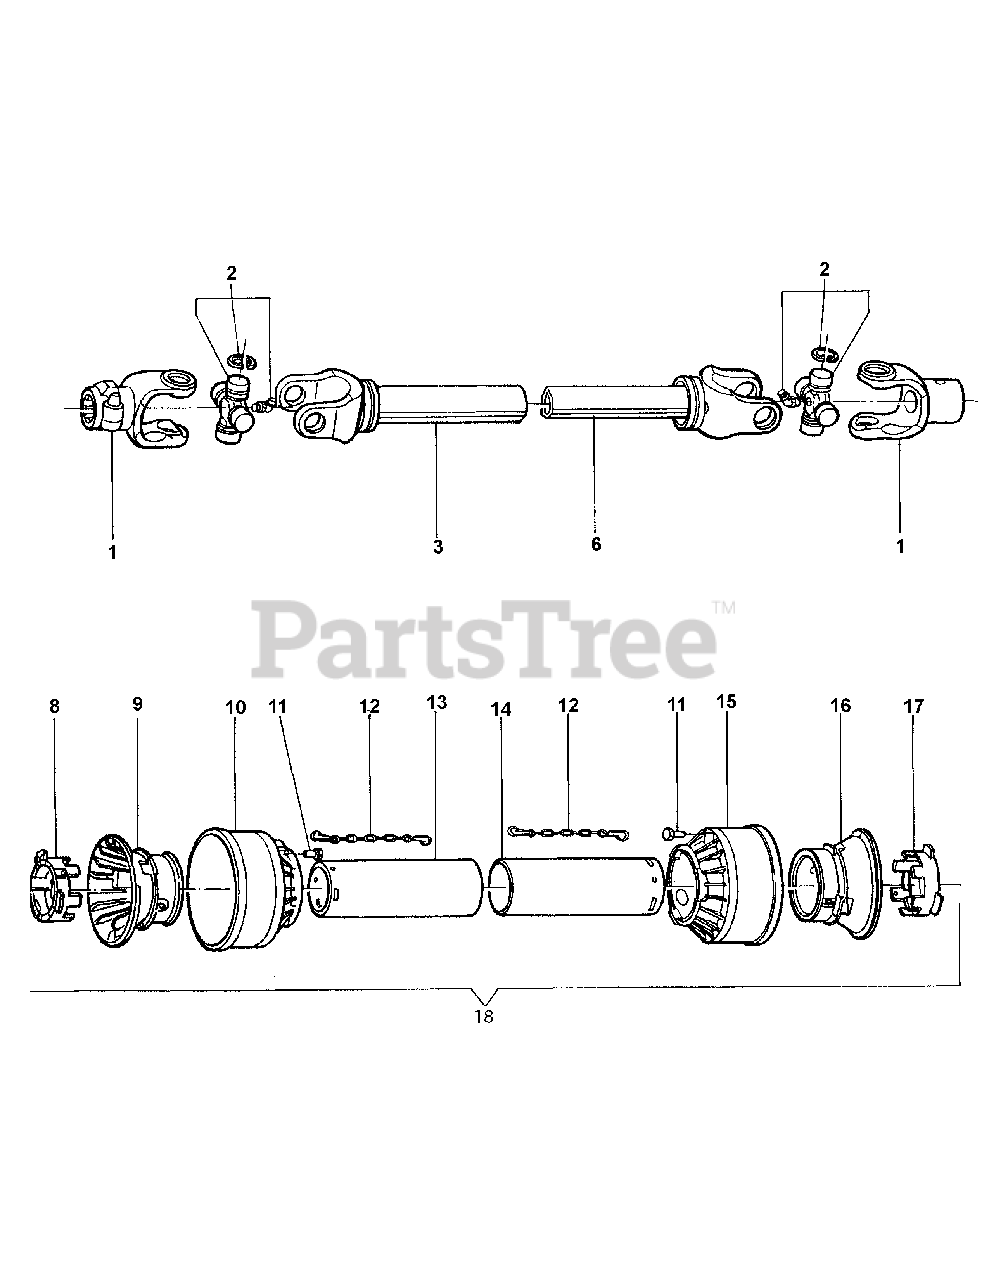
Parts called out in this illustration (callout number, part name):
1	Yoke Assembly
2	Cross Assembly
3	Outer Tube w/Yoke 4'
3	Outer Tube w/Yoke 5'
3	Outer Tube w/Yoke 6'
4	Outer Fastener Ring
5	Inner Fastener Ring
6	Inner Tube w/Yoke 4'
6	Inner Tube w/Yoke 5'
6	Inner Tube w/Yoke 6'
8	Tube Bearing Outer
9	Outer Tube Rigid Cone
10	Soft Cone
11	Pin for Stop Rotation
12	Anit-Rotation Chain
13	Outer Tube 4'
13	Outer Tube 5'
13	Outer Tube 6'
14	Inner Tube 4'
14	Inner Tube 5'
14	Inner Tube 6'
15	Soft Cone
16	Inner Tube Rigid Cone
17	Tube Bearing Inner
17	Shield Complete 4'
17	Shield Complete 5'
17	Shield Complete 6'
18	PTO Complete 4'
18	PTO Complete 5'
18	PTO Complete 6'
